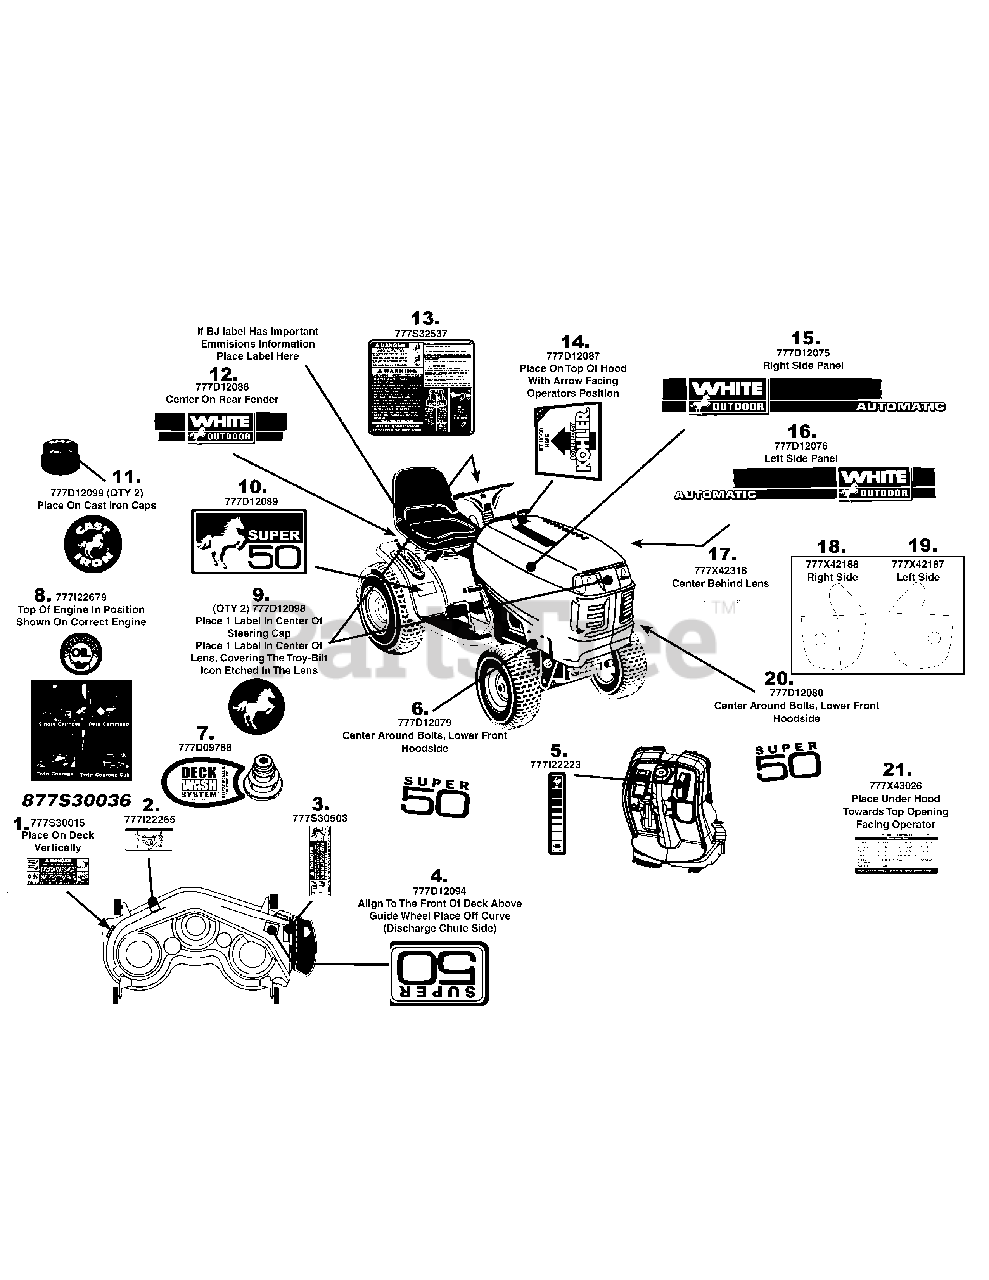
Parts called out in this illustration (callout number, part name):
1	LABEL.RIDER DANGER
2	LABEL-BELT ROUTE
3	LABEL-DANGER CHUTE
4	LABEL-RIDER TOP DECK 50" CUT
5	LABEL-DASH RH
6	LABEL:RIDER:LOWER GRILLE RH
7	LABEL:RIDER:WHITE
8	LABEL-CHECK ENG OIL
9	LABEL-RIDER STEERING CAP WHITE
10	LABEL:RIDER:SD FENDER
11	LABEL-RIDER CAST IRON CAP WHITE
12	LABEL-RIDER REAR FENDER WHITE
13	LABEL:RIDER: AUTO W/CRUISE
14	LABEL-RIDER HOOD T KOHLER
15	LABEL:RIDER:T SYL HS:WHITE AUTO:RH
16	LABEL:RIDER:T SYL HS:WHITE AUTO:LH
17	LABEL-RIDER TROY MID REFL
18	LABEL-RIDER T STYLE GRILL RT
19	LABEL-RIDER T STYLE GRILL LT
20	LABEL:RIDER:LOWER GRILLE LH
21	LABEL:RIDER:PARTS INFO:P60TP
